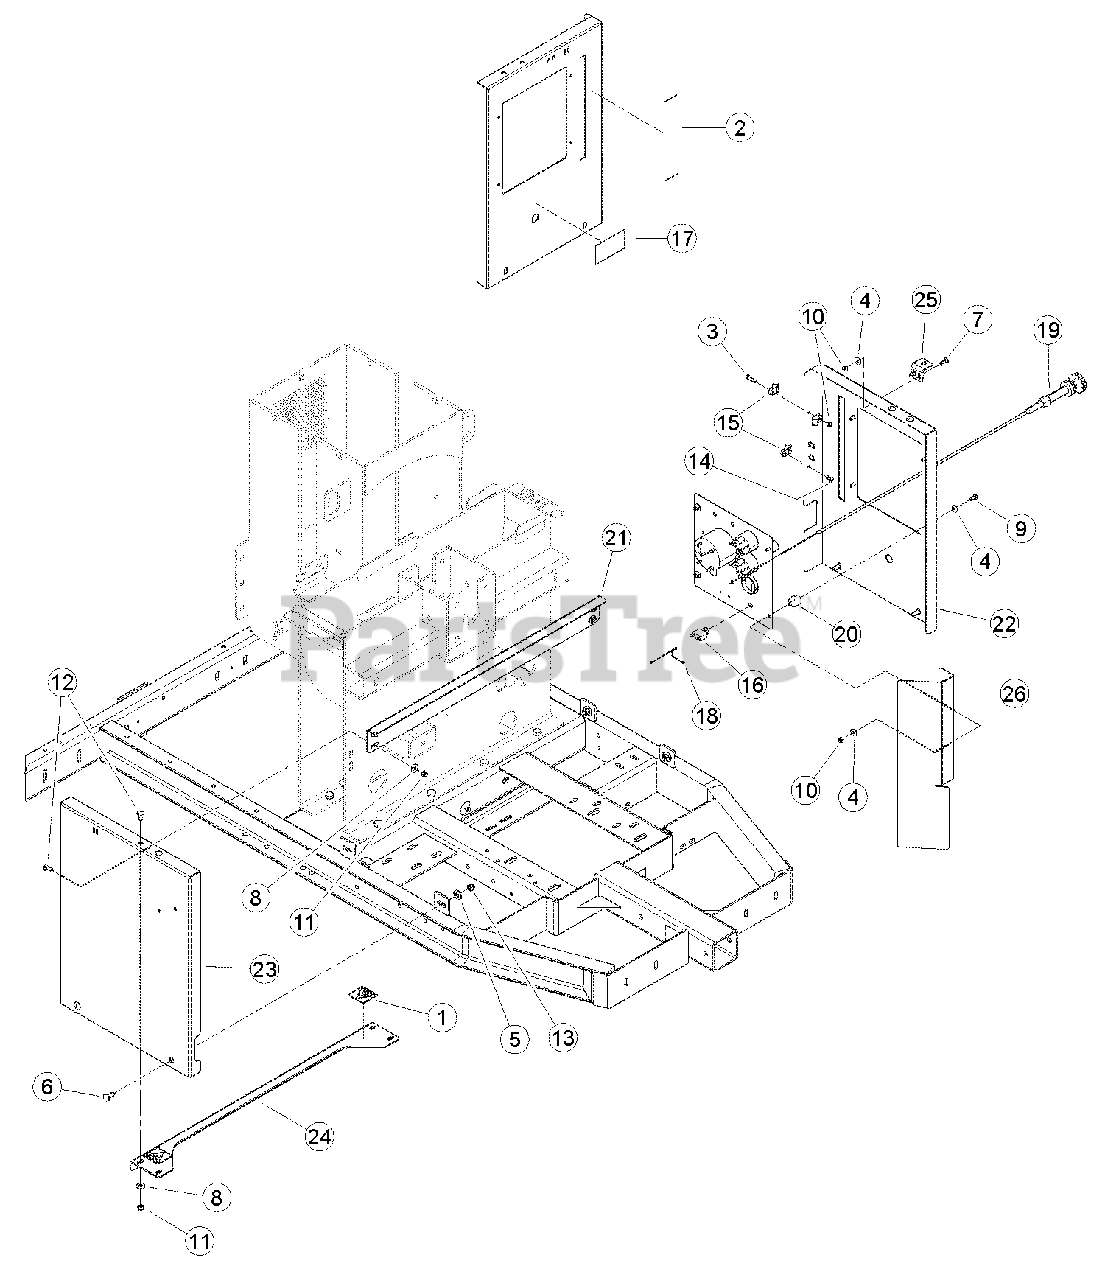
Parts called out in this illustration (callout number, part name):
1	DECAL, SHIELD DANGER ISO
2	DECAL, CHIPPER ENGAGEMENT
3	BOLT, 1/4 X 1 HEX HD GR5 ZP
4	WASHER, 1/4 FLAT ZP
5	WASHER, 3/8 FLAT ZP
6	BOLT, 3/8 X 1 CRG GR5 NC ZP
7	BOLT, 1/4 X 3/4 CRG GR5 ZP
8	WASHER, 5/16 FLAT ZP
9	BOLT 1/4 X 5/8 HEX HD GR5 ZP
10	NUT, 1/4 NE NYLOCK ZP
11	NUT, 5/16 NE NYLOCK ZP
12	BOLT, 5/16 X 3/4 CRG GR5 NC ZP
13	NUT, 3/8 NE NYLOCK ZP
14	RIVET, AL BLIND 1/4 X 3/4 DOME HEAD
15	CLAMP, CABLE MOUNT
16	CIRCUIT BREAKER, 10 AMP RESETTABLE
17	DECAL, FEED SPEED
18	WIRE, IGNITION SPLICE
19	CABLE, DIESEL THROTTLE 30 IN
20	BUMPER, 1" OD W/1/4" STUD
21	PLATE, HOOD SUPPORT
22	SHIELD, ENGINE RIGHT
23	SHIELD, ENGINE LEFT
24	BRACE, ENGINE SHIELD
25	BASE, HOOD LOCK
26	SHIELD, HEAT
